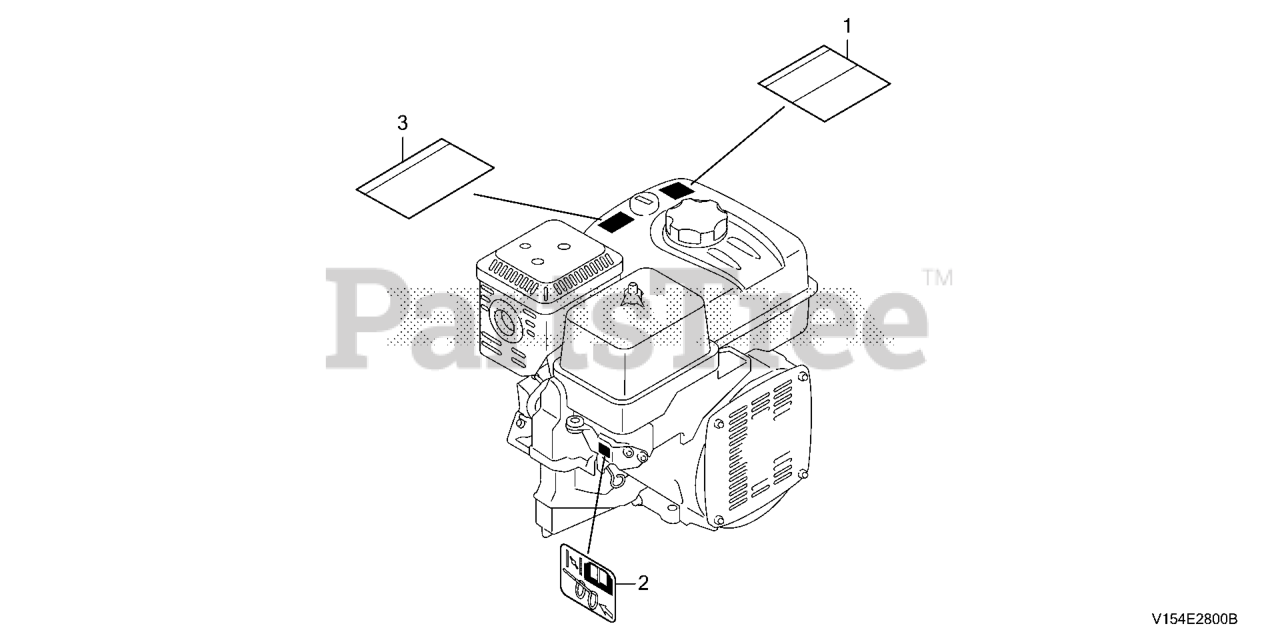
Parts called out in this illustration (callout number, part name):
1	MARK, FUEL WARNING (ENGLISH)
2	MARK, CHOKE
3	MARK, EX. CAUTION (ENGLISH)
